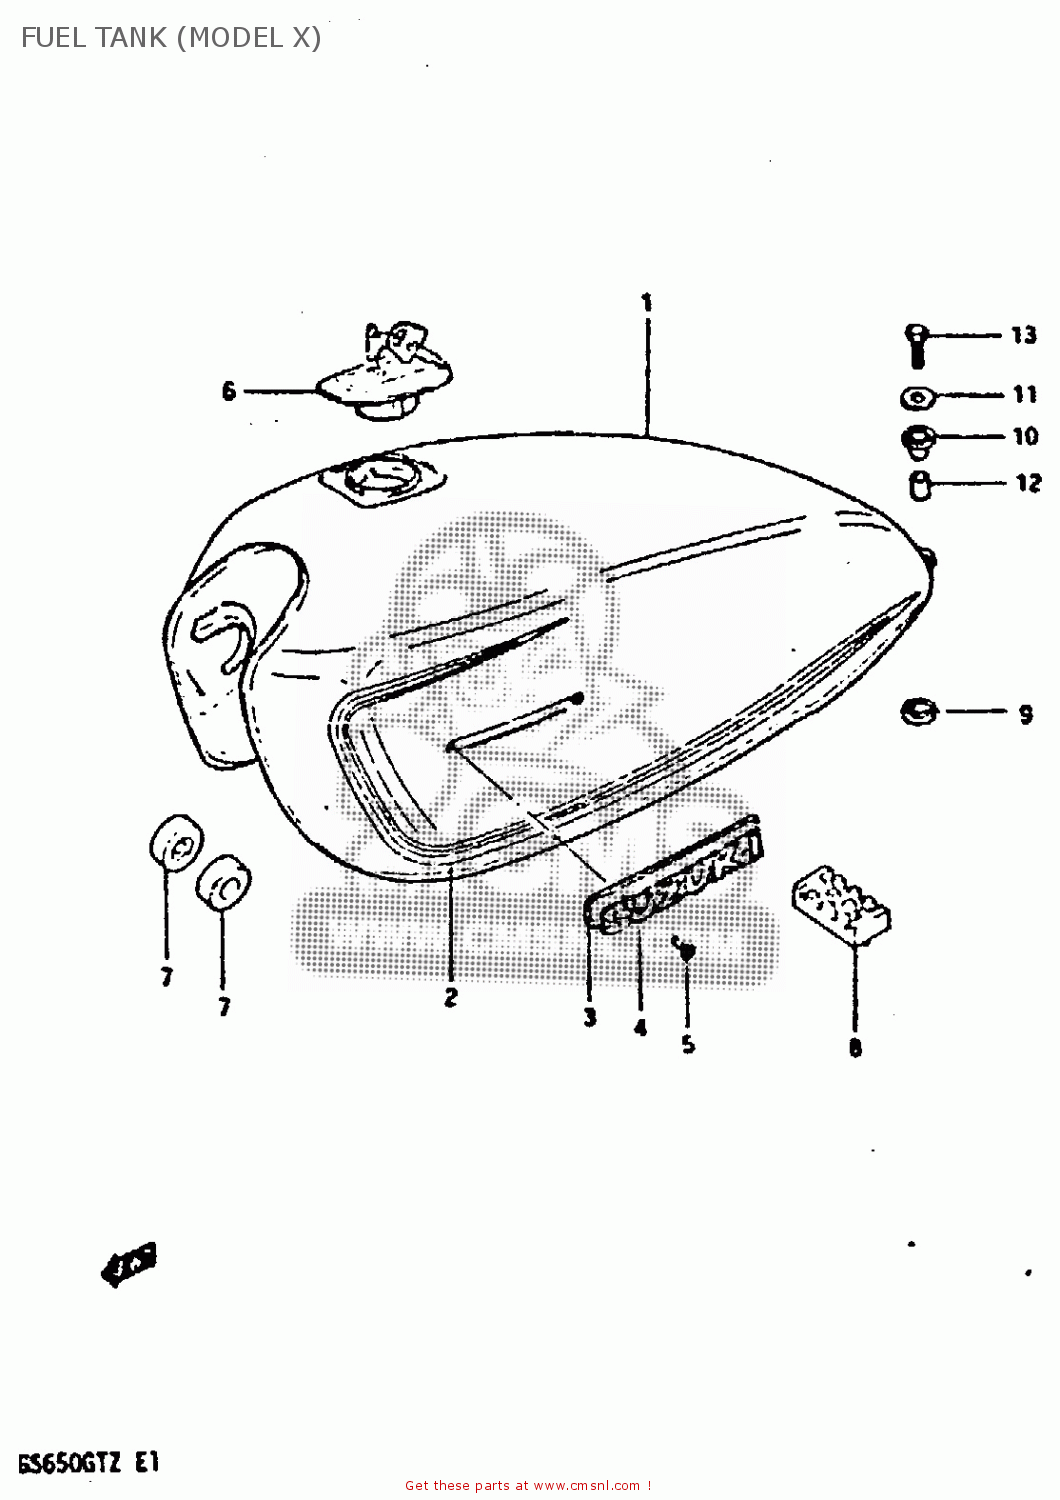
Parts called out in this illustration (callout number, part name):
1	TANK, FUEL (RED)
2	TAPE SET,FUEL TANK
4	EMBLEM
5	SCREW 3X6
6	CAP SET,FUEL TANK
7	CUSHION
8	CUSHION,FUEL TANK CTR
9	CUSHION
10	CUSHION
11	WASHER (6.5X24X1.6)
12	SPACER
13	BOLT
